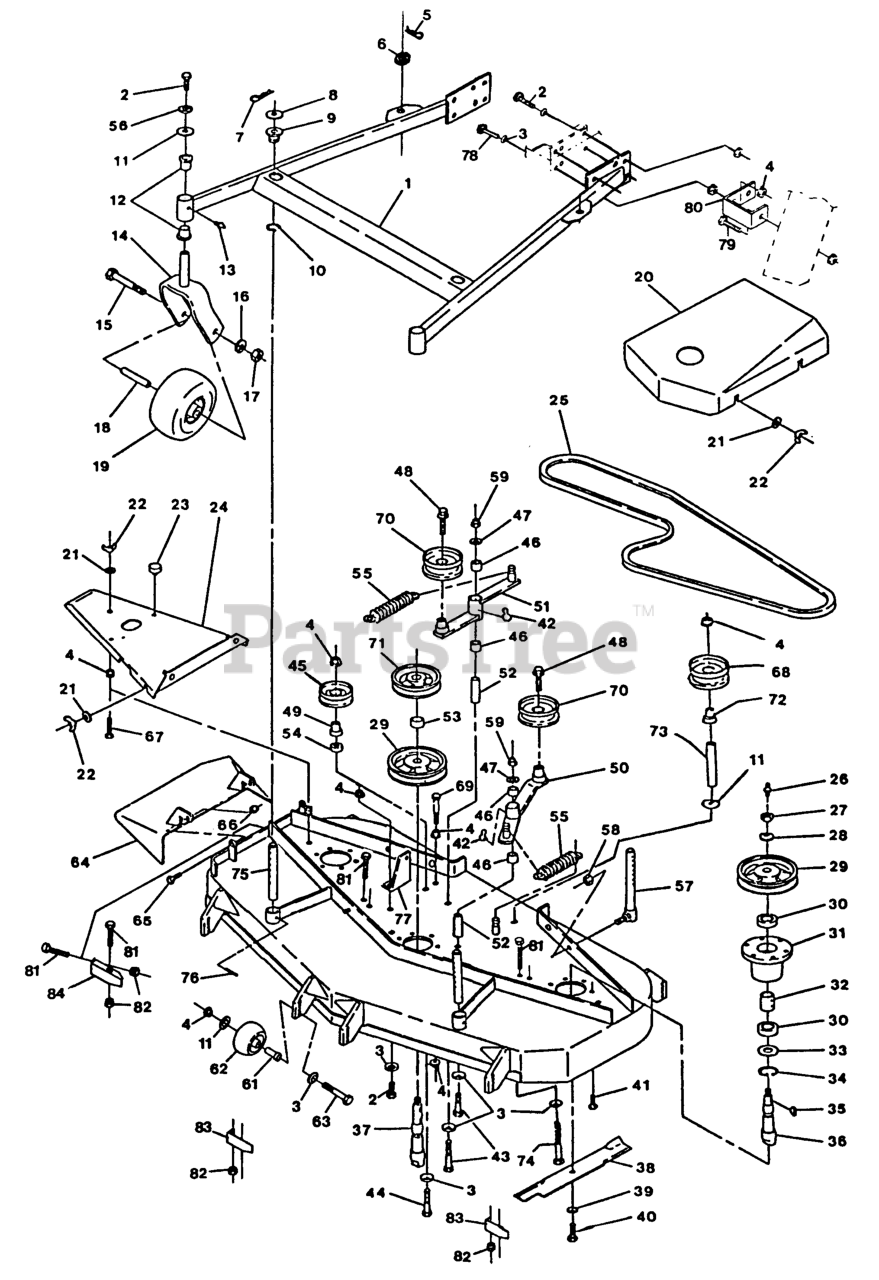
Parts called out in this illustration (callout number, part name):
5	PIN,HAIR COTTER
8	WASHER-FLAT
9	BUSHING-DECK
12	BEARING-FLANGED
22	NUT-WING
24	WLD,DECK COVER
25	BELT-DRIVE, BLADE
28	WASHER-SPRING
29	SHEAVE,BLADE DRIVE
32	SPACER,BEARING
33	SEAL,MECHANICAL DUST
34	RING,SNAP WLDS N5000-244
36	SPINDLE-OUTER BLADE
37	SPINDLE-CENTER BLADE
39	WASHER-SPRING
41	SCRW,TPTTE HH
43	SCREW-HH
46	SLEEVE-BEARING
49	BUSHING-IDLER
50	ASM,IDLER ARM
51	Arm Weld - Dk. Idler Arm
52	BUSHING-PIVOT, IDLER
53	SPACER-TUBE
55	SPRING-EXTENSION
61	BUSHING-ROLLER
62	ROLLER-SCALP, ANTI
68	PULLEY-IDLER
70	IDLER,PULLEY
72	BUSHING,IDLER
73	SPACER-FENDER
75	ROD,DECK SUPPORT
77	BRACKET,SPRING ANCHOR
84	WLD,BAFFLE DISCHARGE
